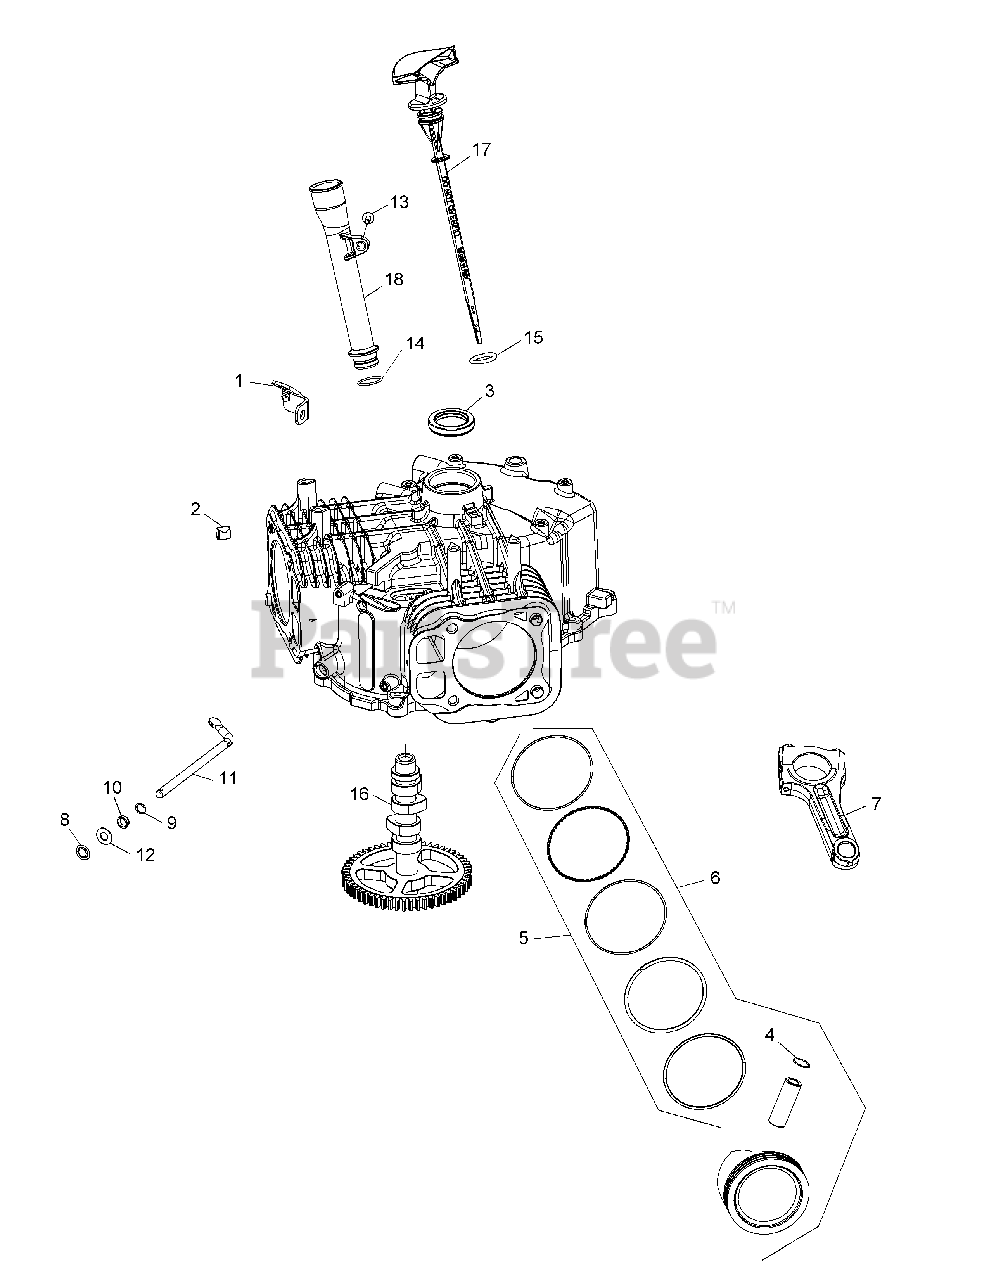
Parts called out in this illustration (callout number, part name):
1	Oil Fill Tube Bracket
3	Oil Seal, 1.78 x 1.26
4	Piston Pin Retainer
5	Piston Ring Set (STD)
5	Piston Ring Set (.08)
5	Piston Ring Set (.25)
5	Piston Ring Set (.50)
6	Piston Kit w/ Ring (STD) (Inc. 4 & 5)
6	Piston Kit w/ Ring (.08)
6	Piston Kit w/ Ring (.25)
6	Piston Kit w/ Ring (.50)
7	Connecting Rod (STD)
7	Connecting Rod (U/S .010) (25mm)
8	Ring Retainer
9	Flat Washer, 11/32"
10	Governor Cross Shaft Seal
11	Governor Cross Shaft
12	Flat Washer, 9 mm
13	Thread Forming Screw
16	Camshaft Assembly
17	Dipstick Assembly
18	Oil Fill Tube Assembly
